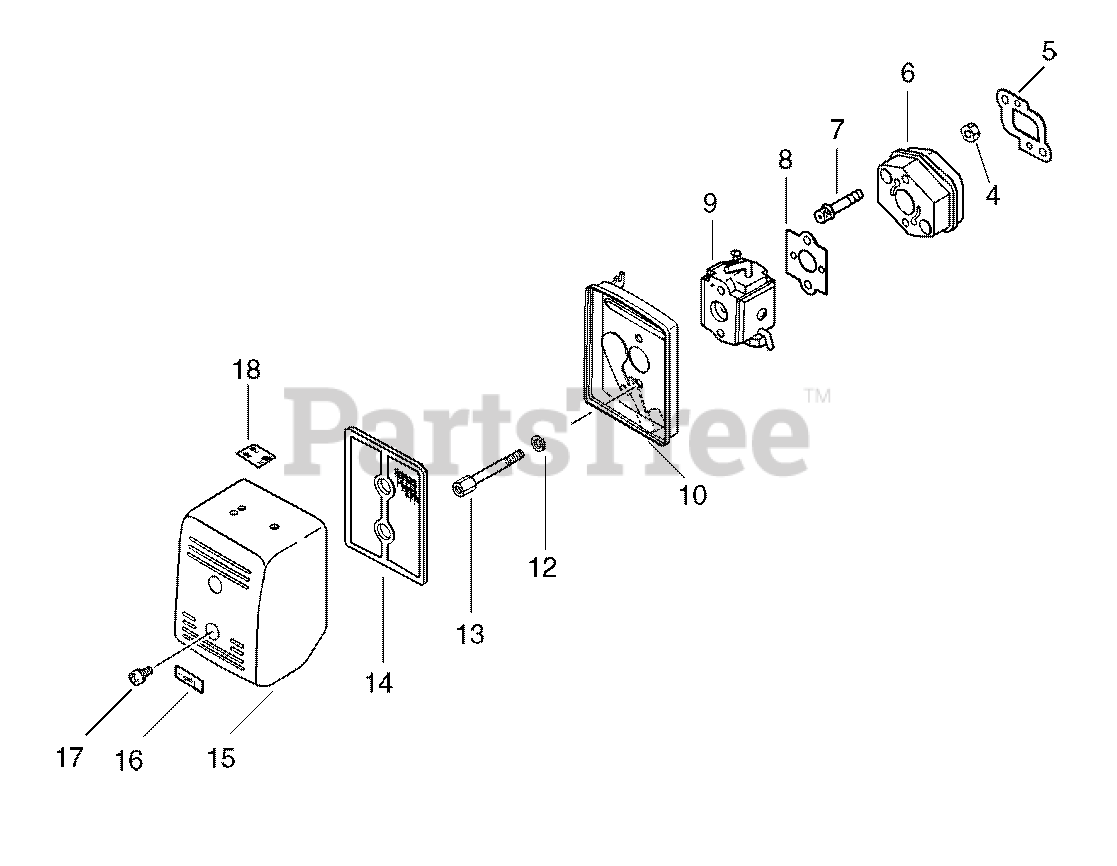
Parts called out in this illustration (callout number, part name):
4	NUT M5
5	GASKET, INTAKE
6	INSULATOR, INTAKE
7	BOLT 5×25
8	GASKET, CARBURETOR
9	CARBURETOR - WT-120B
10	CASE, AIR FILTER
12	WASHER, SPRING 5
14	FILTER, AIR
15	COVER, AIR FILTER
16	LABEL, CHOKE
17	SCREW 4×8
18	LABEL, ADJUSTING
